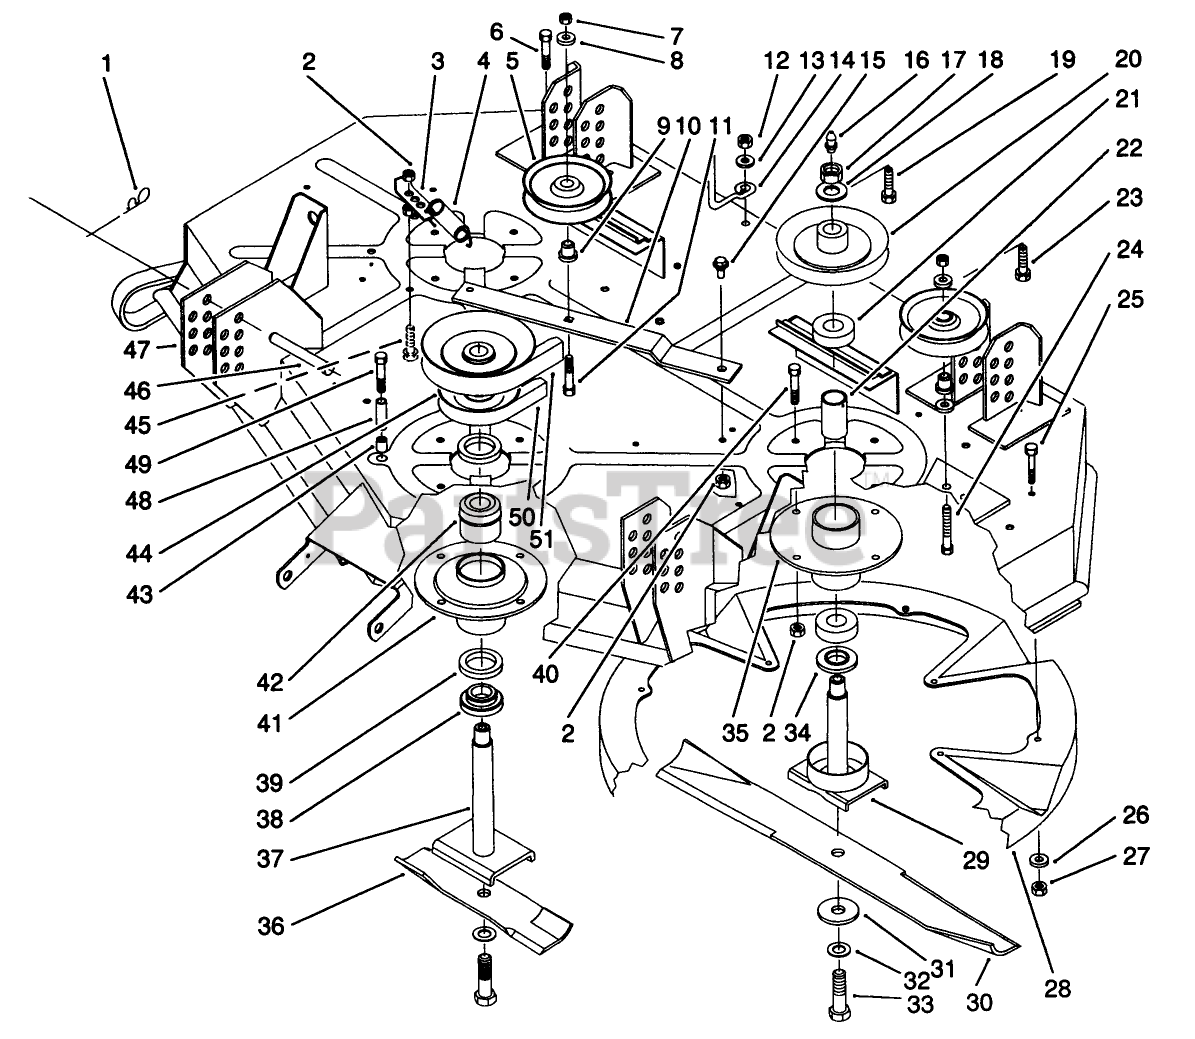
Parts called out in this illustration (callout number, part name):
1	PIN-HAIR
2	NUT-LOCK, NI
3	ANCHOR SPRING R
4	SPRING-EXTENSION, DECK
5	PULLEY-IDLER
6	SCREW-HH
7	NUT-LOCK, NI
8	WASHER-FLAT
9	BUSHING-PULLEY
10	IDLER LEVER R
11	SCREW-HH
12	NUT-HF
13	WASHER-FLAT
14	BELT ROD
15	SCREW-SHOULDER
16	FITTING-GREASE
17	NUT-HEX
18	WASHER
19	SCREW-HH
20	PULLEY-DECK
21	BEARING-BALL
22	SPACER-BEARING
23	SCREW-HH
24	SCREW-HH
25	SCREW-HH
26	WASHER-FLAT
27	NUT-LOCK, NI
28	KICKER INSERT
29	SHAFT-SPINDLE
30	L/H BLADE
31	BLADE WASHER
32	WASHER-LOCK
33	SCREW-BLADE
34	SPACER-SPINDLE
35	HOUSING-SPINDLE
36	CENTER BLADE
37	SHAFT-SPINDLE
38	SPACER
39	SEAL-OIL
40	SCREW-HH
41	SPINDLE HOUSING
42	BEARING ASM
43	INSERT-THREADED
44	CENTER PULLEY WA
45	SCREW-HH
46	PIN-CLEVIS
47	DECK W/DECALS
48	OUTER TUBE SPACER
49	SCREW-HH
50	V-BELT
51	V-BELT
